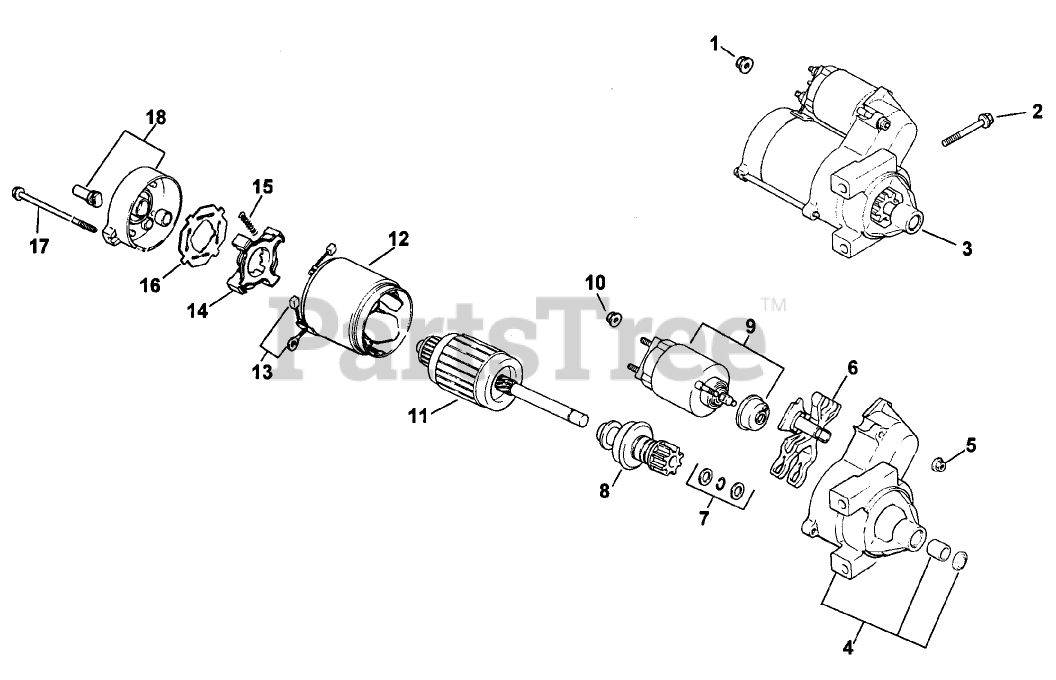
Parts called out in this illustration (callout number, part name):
1	NUT-FLANGE (M8X1.25)
2	SCREW-FLG (M8X1.25X80)
3	Starter, solenoid shift (Includes 4-18)
4	Cap-End, Drive
5	Nut-Starter
6	LEVER-DRIVE, STARTER
7	STARTER REPAIR KIT
8	Drive-Pinion
9	Solenoid
10	Nut
11	Armature-Starter
12	Frame w/Brushes ASM
13	Kit, brush & spring (Includes 15)
14	Holder-Brush
15	Spring-Brush
16	Insulator
17	Bolt-Thru
18	Commutator-cap, end
